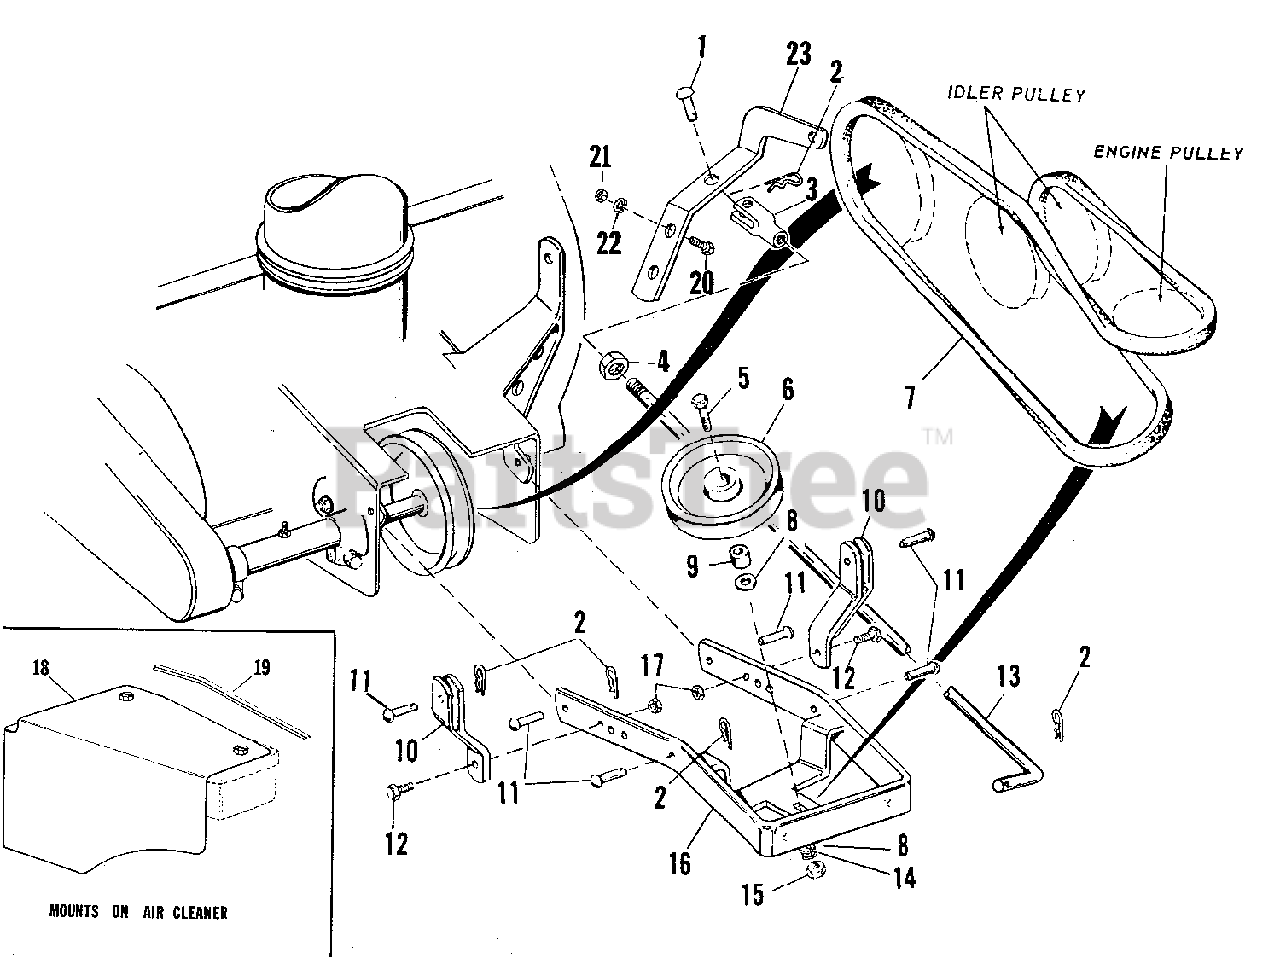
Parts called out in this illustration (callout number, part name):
3	YOKE, End Adjusting
4	NUT, Hex, 1/2-20
5	SCREW, Hex Cap, 3/8-16 x 3/4
8	WASHER, Flat, 3/8
10	ARM, Support
12	SCREW, Hex Cap, 3/8-16 x 1
14	WASHER, Lock, 3/8"
15	NUT, Hex, 3/8-16
17	NUT, Hex, Lock, 3/8-16
18	DEFLECTOR, Heat
19	FILM, Shield
20	SCREW, Hex Cap, 3/8-16 x 1
21	NUT, Hex, 3/8-16
22	WASHER, Lock, 3/8"
23	SUPPORT, Spout Adjusting Rod
